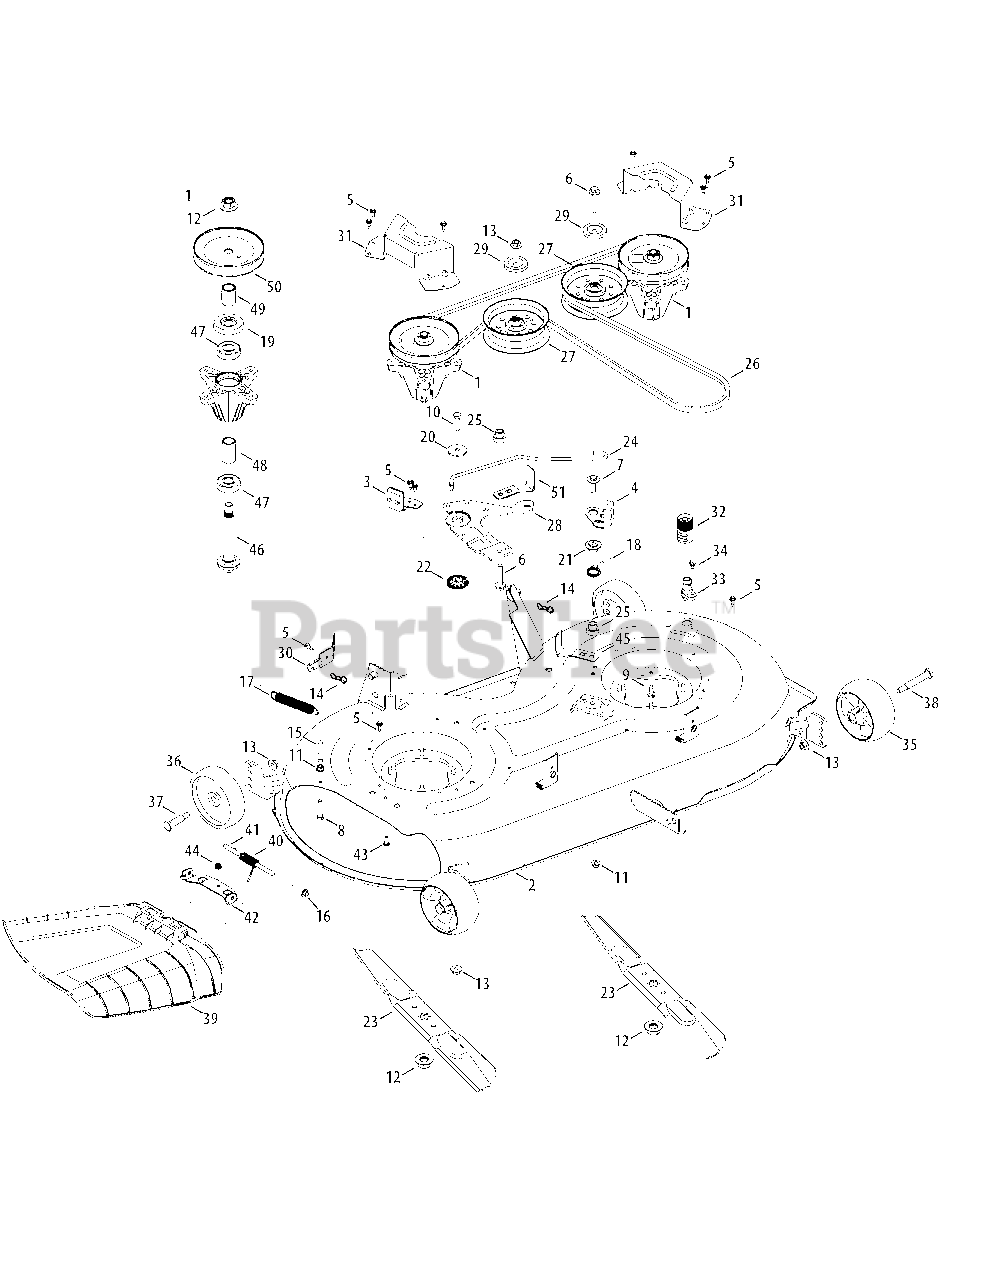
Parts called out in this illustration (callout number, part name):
1	Spindle Ass’y, Pulley, 6.3 Dia
2	Deck, 42"
3	Brake Assembly, Deck, RH
4	Brake Assembly, Deck, LH
5	Screw, M6-1 x .625
6	Hex Cap Screw, 3/8-16 x 2.00
7	Hex Cap Screw, 5/16-18 x 1.25
8	Hex Cap Screw, 5/16-18 x 1.00
9	Screw, Self-tapping, 5/16-18, 0.750,
10	Hex Cap Screw, 3/8-16 x 1.25
11	Nut, Flange Lock, 5/16-18, Nylon
12	Nut, Flange, 5/8-18
13	Flange Lock Nut, 3/8-16
14	Bow-Tie Cotter Pin
15	Vinyl Cap, .29 x .50
16	Push Cap
17	Spring, Extension, .750 x .477
18	Spring, Torsion, LH Brake
19	Bearing Shield
20	Flat Washer, .39 x 1.5 x .134
21	Shoulder Spacer, .75 x .145
22	Shoulder Spacer, .854 x .191
23	Blade, Cut, 21.23" 2-In-1
24	Rod, Brake, Deck
25	Shoulder Spacer, Idler
26	Belt, V-Type, A Sec x 99.75
27	Pulley, Idler, 4.50" Dia.
28	Idler Bracket
29	Pulley Cap
30	Bracket, Cable, PTO
31	Belt Cover
32	Coupler, Water
33	Deck Wash Nozzle
34	Shoulder Screw, 1/4-20 x 0.50
35	Wheel, Deck, 5.0 Dia. Ball
36	Wheel, Deck 5.0 x 1.38
37	Bolt, Shoulder, .496 x 1.525, 3/8-16
38	Bolt, Shoulder, .496 x 2.50, 3/8-16
39	Chute Deflector Assembly
40	Spring, Torsion, .440 ID x 1.75
43	Hex Cap Screw, 1/4-20 x .62
44	Nut, Flange Lock, 1/4-20, Nylon
45	Belt Keeper
46	Shaft, Spindle, 5.75
47	Bearing, Ball, .787id x 1.85 Od x .551
48	Spacer, .792 x 1.060 x 1.860
49	Spacer, .800 x 1.10 x 1.470
50	Pulley, Deck, 5.40 Dia.
